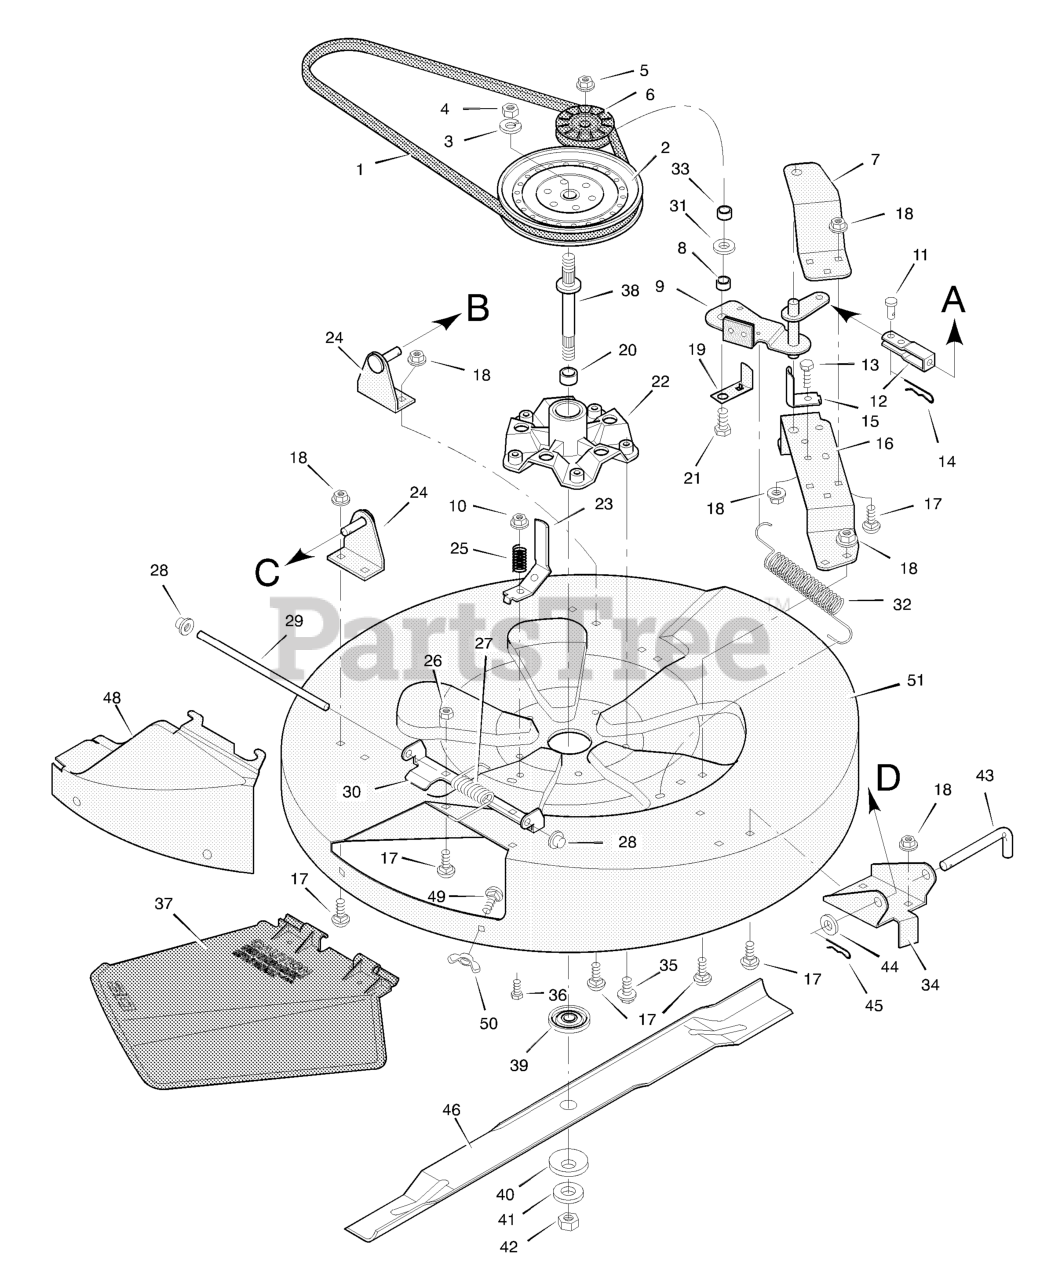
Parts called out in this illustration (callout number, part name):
1	Belt, Mower Drive
2	Pulley, Splined
3	Lockwasher
4	Locknut, Hex
5	Nut, Hex
6	Pulley, Idler
7	Bracket, Upper Idler
9	Assembly, Blade Idler
10	Locknut, Flange
11	Pin, Clevis
13	Bolt, Hex
14	Pin, Hair
15	Guide, Belt
16	Bracket, Lower Idler
17	Bolt, Carriage
18	Nut, Flange
19	Guide, Belt
21	Bolt, Hex
22	Housing, Mandrel
23	Guide, Belt
24	Bracket, Hanger
25	Spring, Compression
26	Nut, Hex
27	Spring - Torsional
28	Push On Cap
30	Hinge, Chute Deflector
32	Spring, Extension
34	Bracket, Front
36	Bolt, Hex
37	Deflector, Chute
38	Mandrel
39	Adapter, Blade
40	Washer, Belleville
41	Washer, Hardened
42	Nut, Hex
43	Pin, Pull
45	Pin, Hair
46	Blade, Mulching
48	Plate, Mulcher
49	Bolt, Carriage
50	Wingnut
